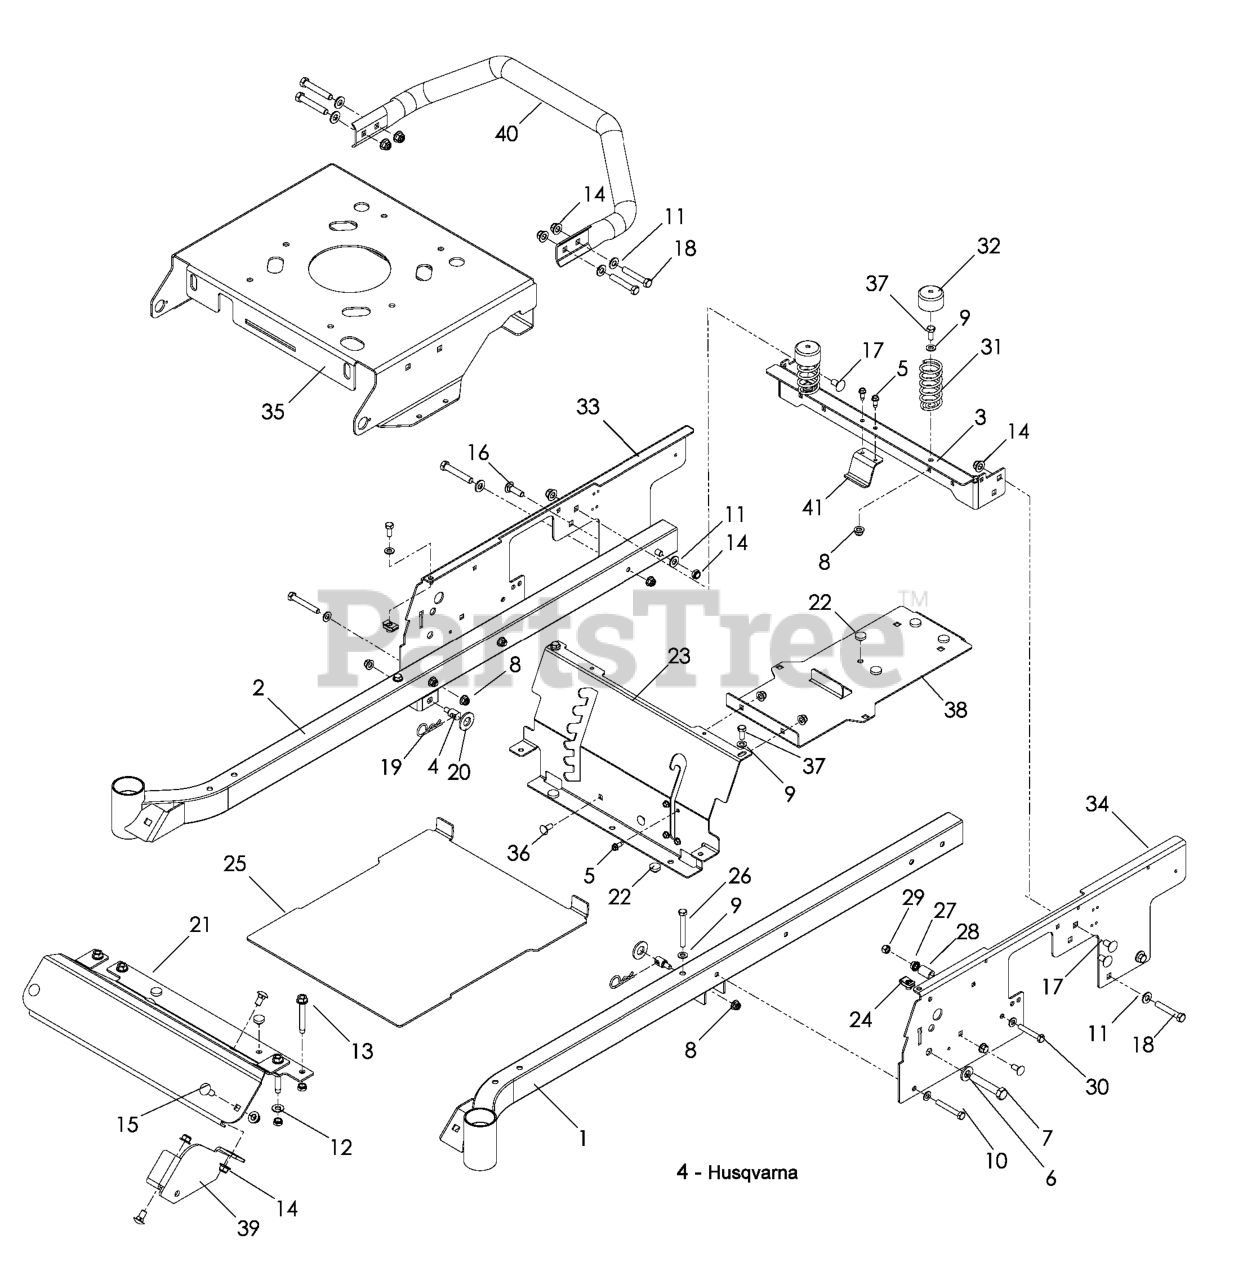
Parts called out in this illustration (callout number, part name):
1	FRAME TUBE, LH, ORG
2	FRAME TUBE, RH, ORG
3	SUPPORT, REAR SEAT, ORG
4	STUD.FASTNER.W/ANTI-ROTATE
5	SCREW 1/4 X 5/8
6	WASHER 1/2" FLAT
7	HCS 1/2C X 2 3/4
8	5/16-18 NYLOC FLANGE NUT
9	FLAT WASHER 5/16 SAE
11	WASHER 3/8 SAE FLAT
12	NUT HEX 3/8-16 NYLON, THIN
13	ENGINE BOLT, SPECIAL
14	NUT 3/8-16 HEX FLG NYLOC ZD
15	RHSNB 3/8C X 1
16	RHSNB 3/8-16 X 1-1/4
17	RHSNB 3/8-16 X 3/4 GR5 ZD
18	HCS 3/8C X 2 1/4
19	HAIRPIN #4
20	WASHER 5/8 FLAT
21	FOOT.REST.30/38.ORANGE
22	GROMMET, BUMPER
23	PANEL, SEAT SUPP, ORG
24	U-CLIP 5/16-18 NUT RETAINER
25	FOOT PLATE, NARROW, ORG
26	HCS 5/16C X 2-3/4
27	NUT 5/16C WHIZ
29	NUT 5/16 NYLOC
30	HCS 5/16-18X2
31	SEAT SPRING
32	SPRING CAP
33	PLATE, RT SIDE, ORG
34	PLATE, LT SIDE, ORG
35	PLATE, ENGINE, ORG
36	BOLT 5/16C X 3/4" CARRIAGE
37	HCS 5/16C X 3/4
38	SUPPORT, TANK/BATT, BLK
39	BRACKET, FRONT DECK, BLK
40	IMPACT BAR, ORG
41	HOLDING DEVICE, FUEL TANK, BLK
